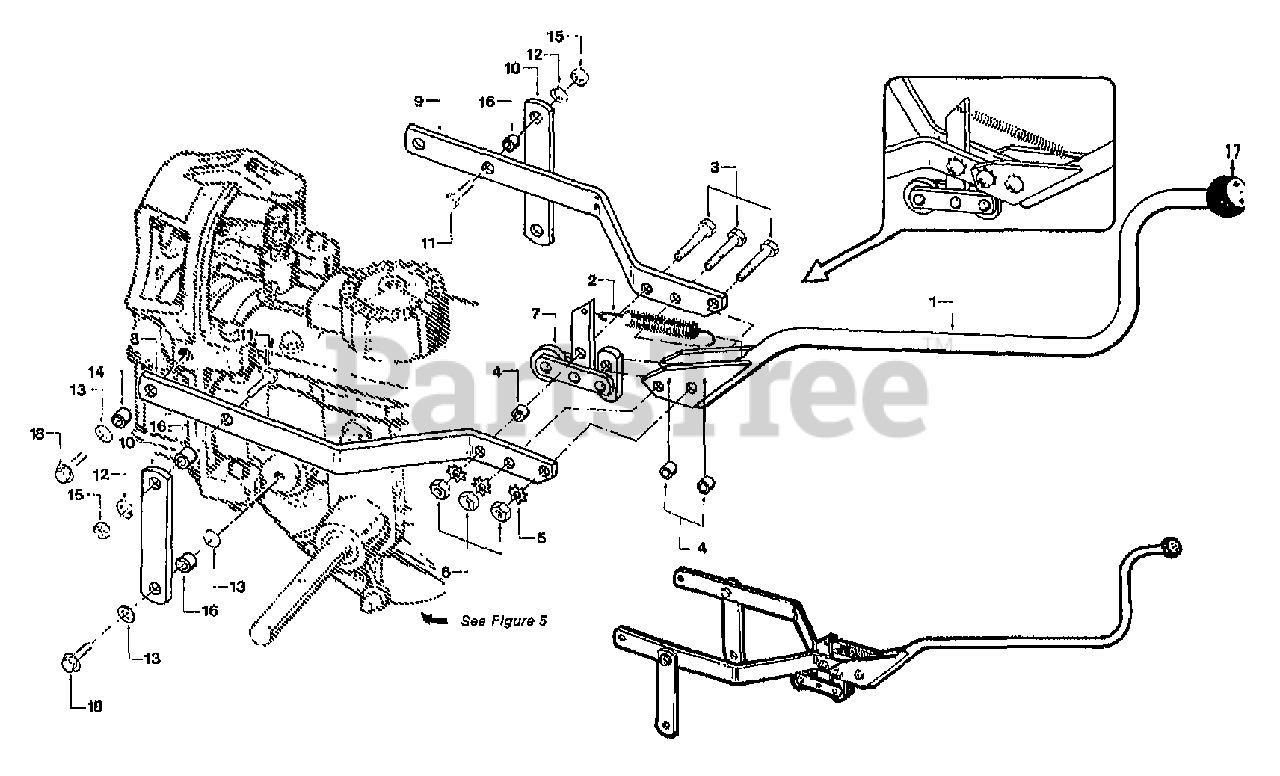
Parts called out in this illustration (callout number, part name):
1	ASSM-FOR/REV LEVER
2	SPRING-.436 X 3.25
3	SCR-HH 5/16-18X1.5 G5 ZP
4	BUSHING-.5X.316X.375 PM
5	WASHER-LK .312 EXT TOOTH
6	NUT-HEX 5/16-18 ZP
7	ASSM-ROLLER PAINT
8	YOKE-LH RED
9	YOKE-RH RED
10	YOKE-RED 2164
11	SCR-HH 3/8-16X1.0 G5 ZP
12	WASHER-LK .375 @ DEPL
13	WASHER-FLAT 3/8 SAE
14	BUSHING-.5X.375X.325
15	NUT-HEX 3/8-16 ZP
16	BUSHING-.5X.375X.3
17	KNOB, PLASTIC
18	SCR-HFLK 3/8-16X1.00 ZP
